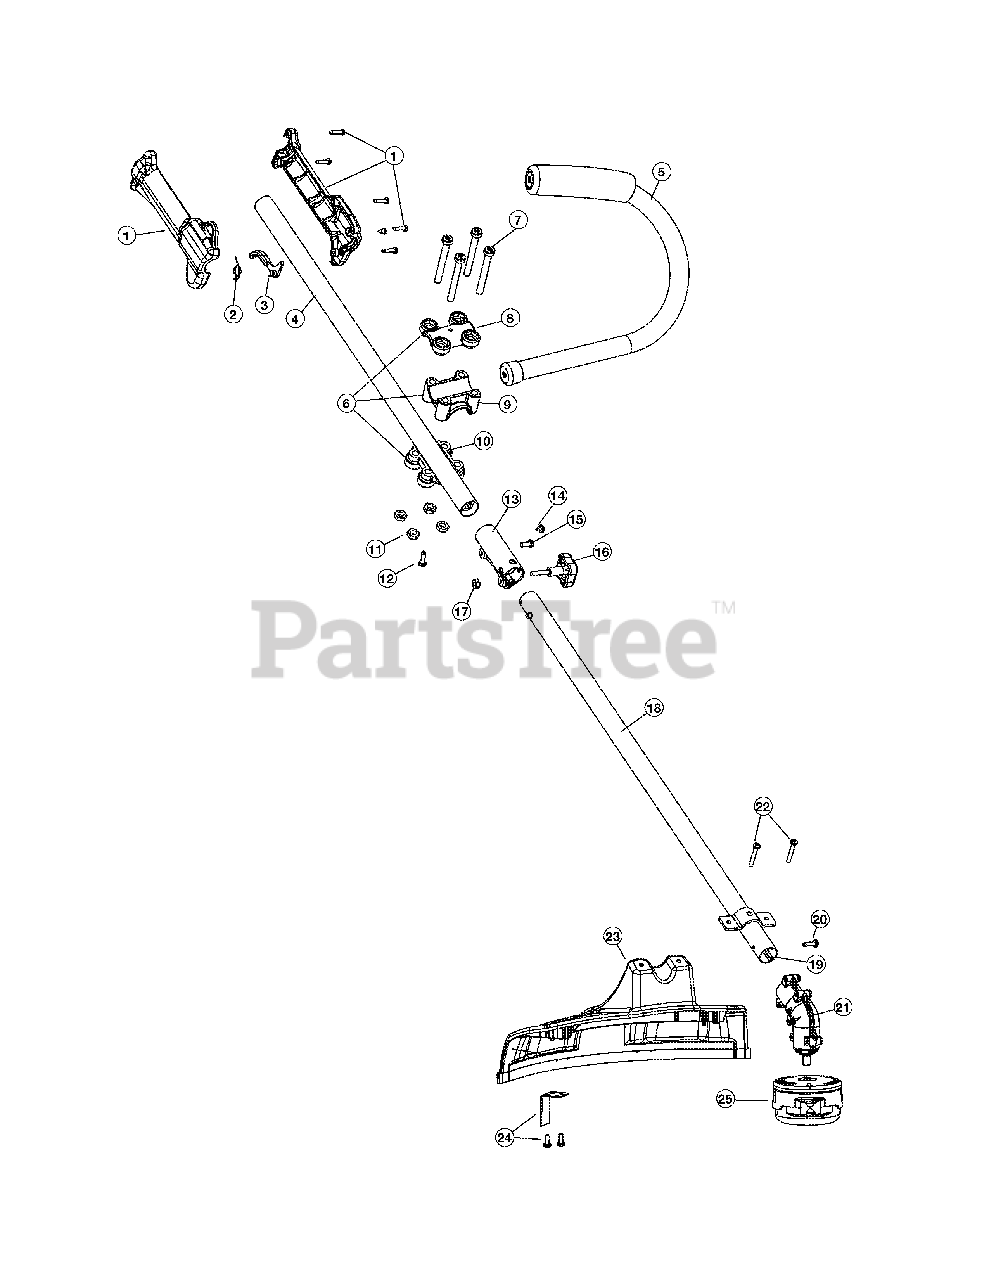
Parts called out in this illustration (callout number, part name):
1	Throttle Housing Assembly (includes 2 & 3)
2	Throttle Trigger Spring
3	Throttle Trigger
4	Upper Drive Shaft Housing Assembly
5	J-Handle Assembly
6	Handle Bracket Assembly (includes 7-12)
8	Upper Handle Clamp
9	Middle Handle Clamp
10	Lower Handle Clamp
12	Anti-Rotation Screw
13	Split Boom Coupler (includes 14-17)
16	Adjustment Knob (Includes 17)
17	Knob Retaining Nut
18	Lower Drive Shaft Housing Assembly
19	Lower Flexible Drive Shaft
20	Anti-Rotation Screw
21	Gear Box Assembly (includes 20)
22	Shield Mounting Screws
23	Shield Assembly (includes 5 & 7)
24	Blade Assembly
25	Cutting Head Assembly
